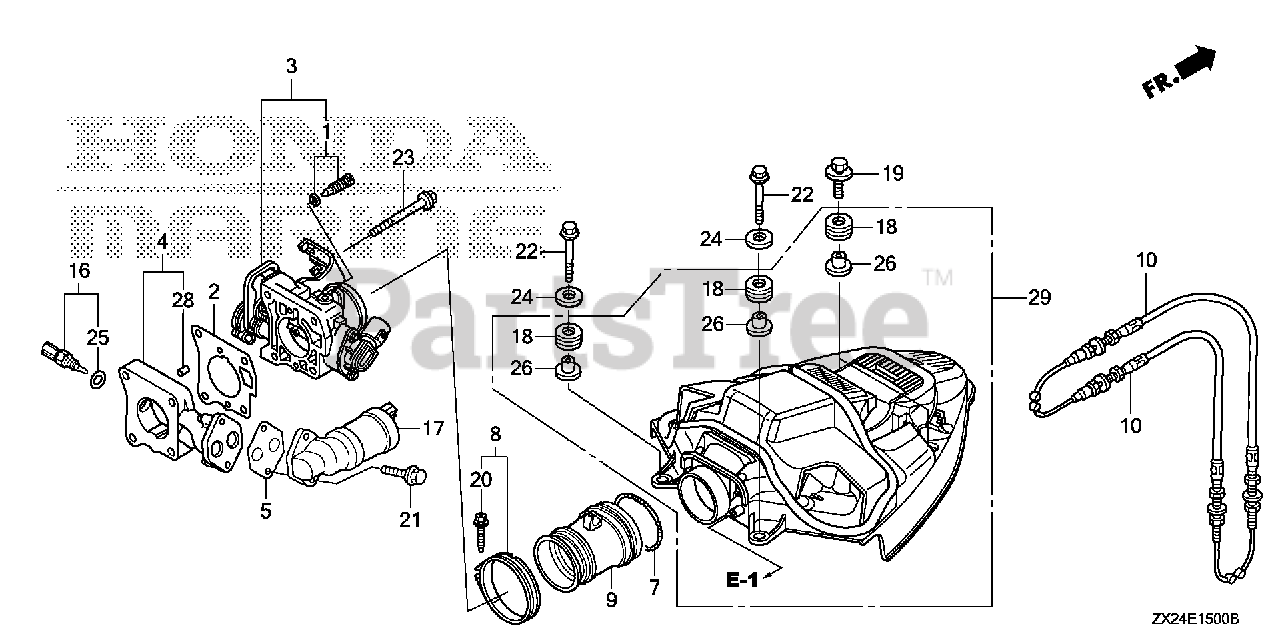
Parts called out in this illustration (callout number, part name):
2	GASKET, THROTTLE BODY
3	BODY ASSY., THROTTLE
4	SPACER, THROTTLE BODY
5	GASKET, EAC VALVE
7	SPRING, AIR FLOW TUBE
8	BAND, AIR FLOW
9	GROMMET, MUFFLER
10	CABLE, THROTTLE
16	SENSOR ASSY., AIR TEMPERATURE
17	VALVE ASSY., EAC
18	GROMMET, CASE (LOWER)
19	BOLT-WASHER (6X25)
20	BOLT-WASHER (5X30)
21	BOLT, FLANGE (6X22)
22	BOLT, FLANGE (6X60)
23	BOLT, FLANGE (8X65)
24	WASHER, PLAIN (6MM)
26	COLLAR, MODULE IGNITION CONTROL CASE (CDI)
28	PIN, DOWEL (6X10)
29	COVER ASSY., COOLING FAN
